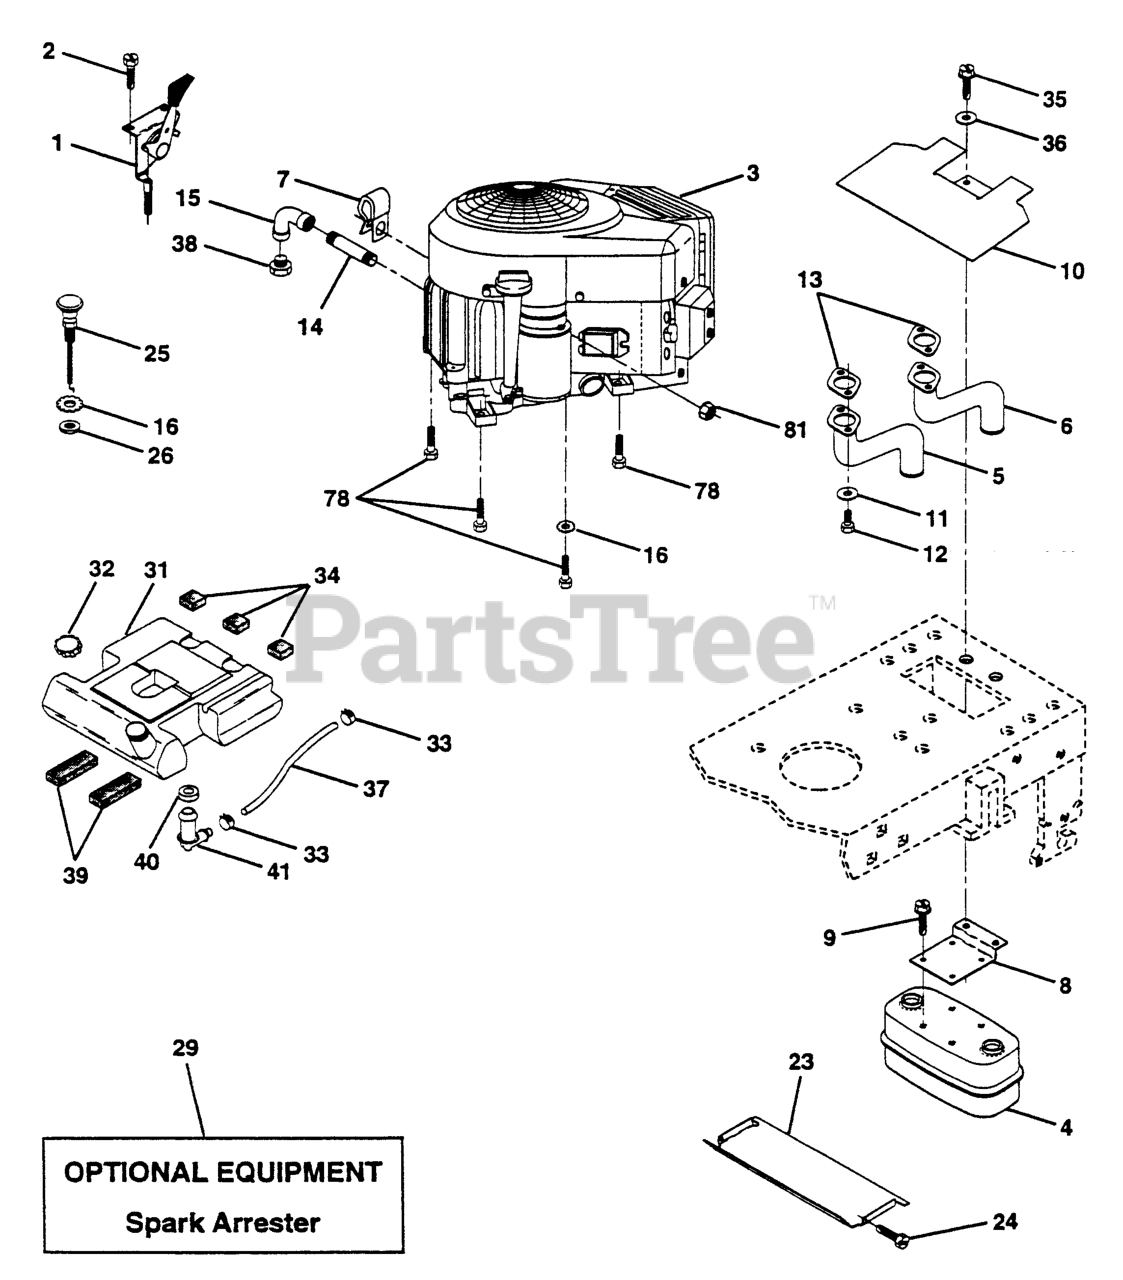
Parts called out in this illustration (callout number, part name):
1	CONTROL.THROT.RH.BLK.FLG.44.75
2	SCREW LT
4	MUFFLER
5	TUBE ASSY EXH LH
6	TUBE ASSY EXH RH
7	CLIP T
8	BRACKET MUFFLER
9	SCREW ST
10	SHIELD HEAT LT
11	Washer
12	Bolt
13	Muffler Gasket
14	Nipple Pipe 3/8 Npt X 4-1/2"
15	ELBOW
16	LOCKWASHER
23	HEAT SHIELD
25	CHOKE CONTROL
26	NUT
29	KIT.SPARK ARRESTOR 794945 B&S
31	FUEL TANK
32	FUEL CAP
33	HOSE CLAMP
34	PAD-SPACER LT
35	SCREW.THDROL.5/16-18X3/4.TTY
36	WASHER
37	FUEL LINE 54"
38	Plug Oil Drain
39	PAD IDLER TI
40	BUSHING OUTLET T
41	STEM FUEL TANK
78	SCREW
81	NUT
